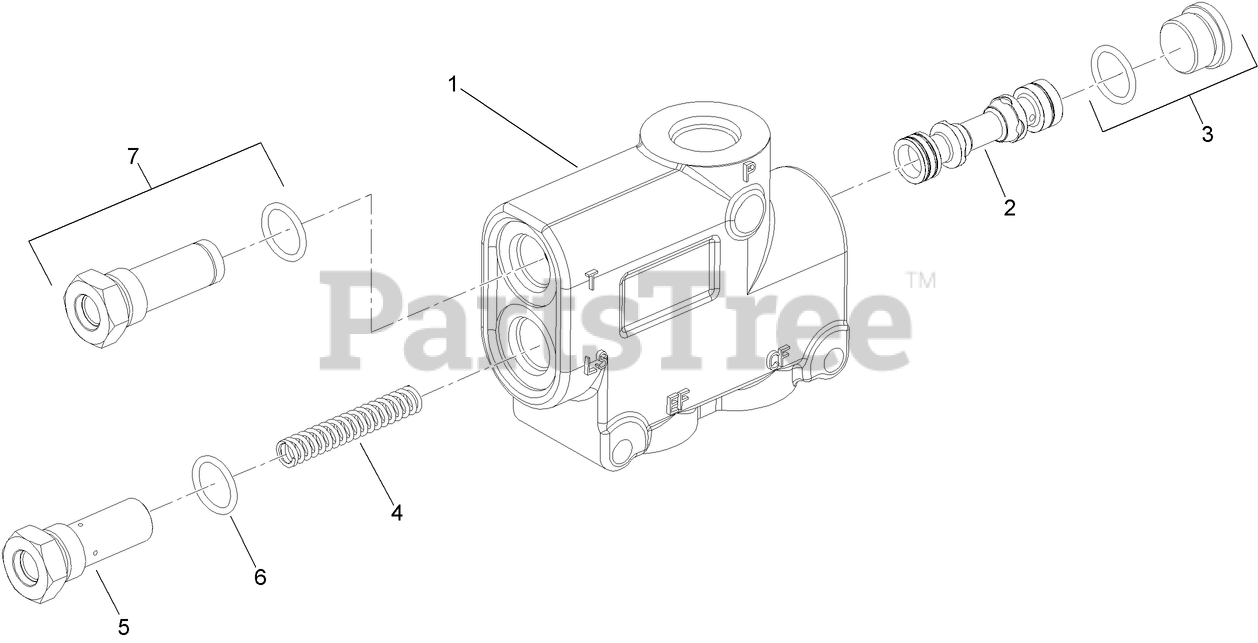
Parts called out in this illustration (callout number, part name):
1	BODY-VALVE
2	SPOOL-Valve
3	PLUG ASM
4	SPRING-SPOOL
5	PLUG-RETAINING, SPOOL SPRING
6	O-RING
7	CARTRIDGE-VALVE, RELIEF
